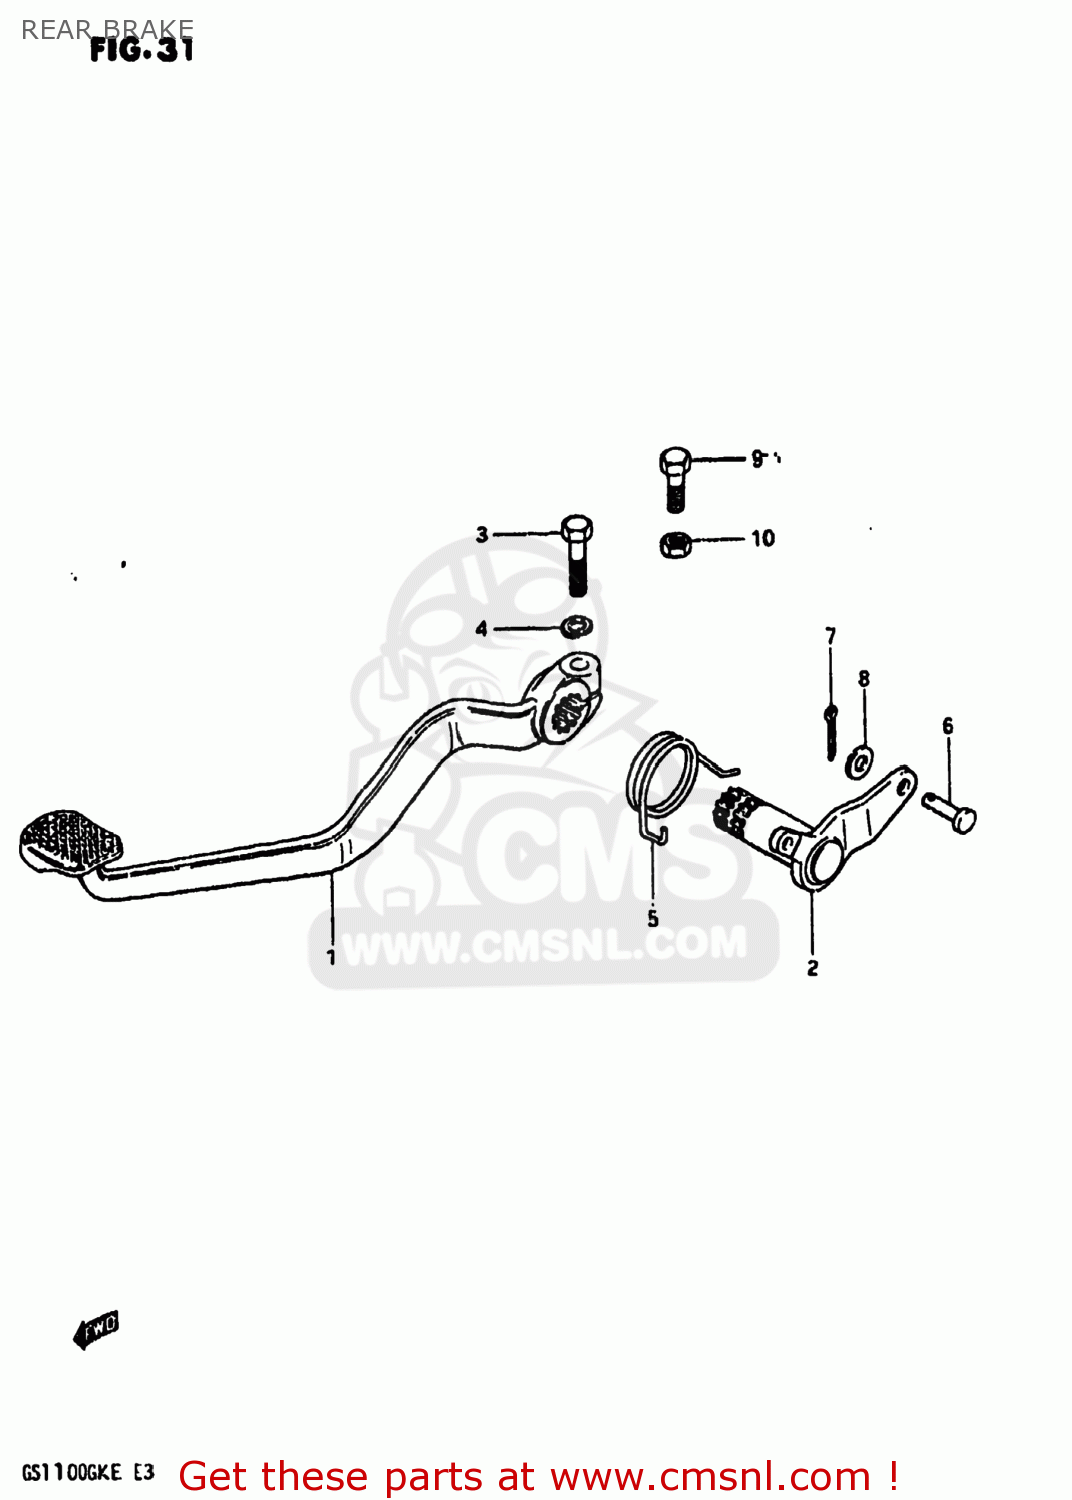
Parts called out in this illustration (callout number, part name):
1	PEDAL,BRAKE
2	ARM,BRAKE PEDAL ROD
3	BOLT
4	LOCK WASHER
5	SPRING
6	PIN
7	PIN
8	WASHER
9	BOLT
10	NUT
